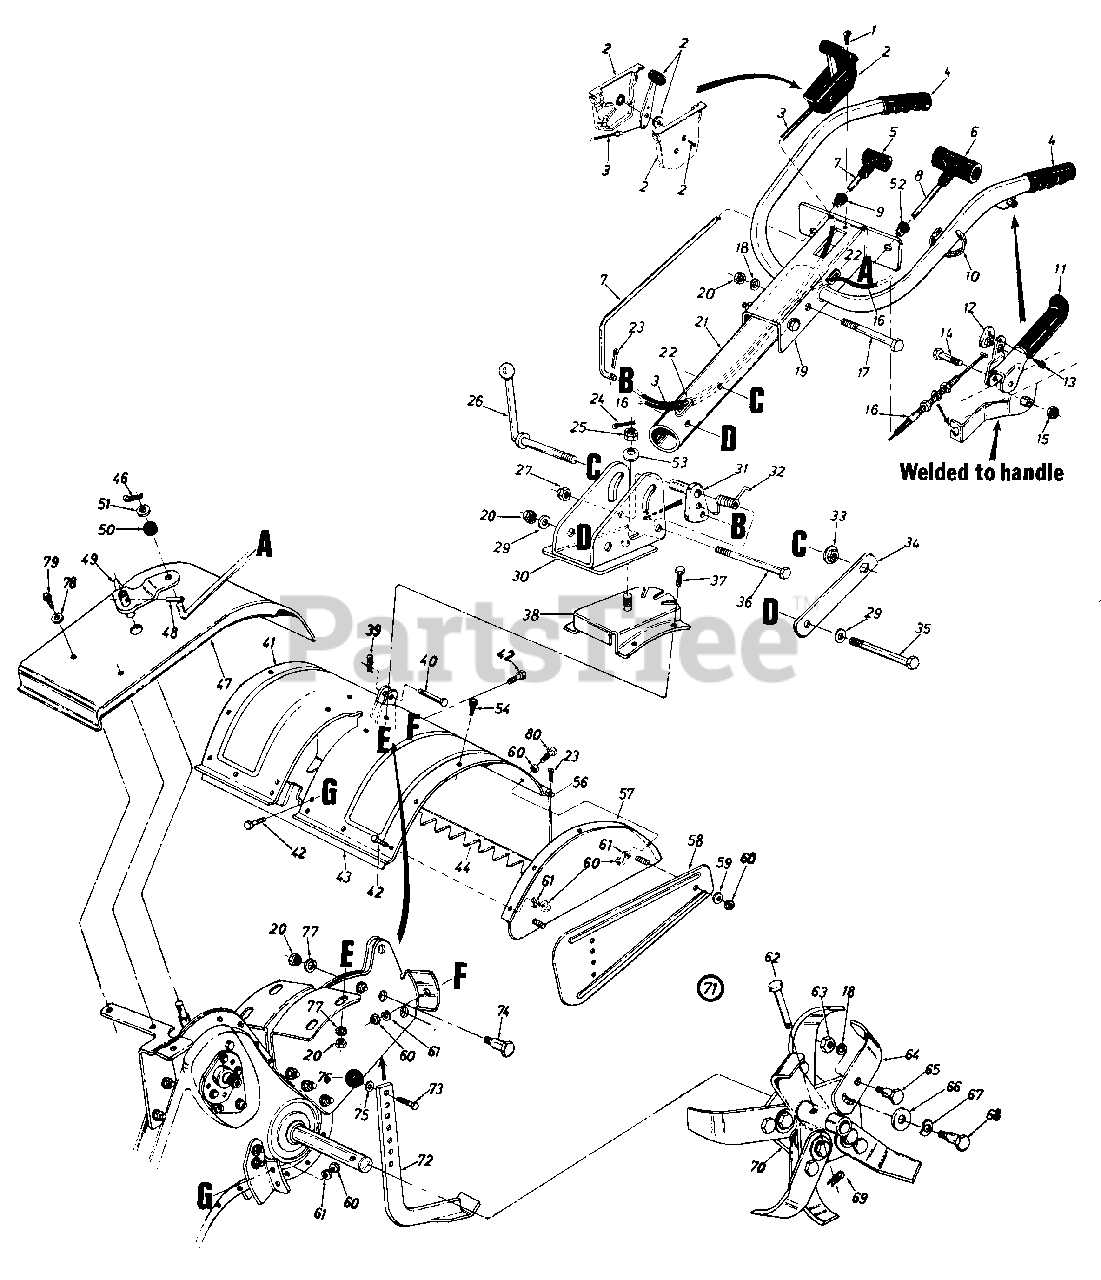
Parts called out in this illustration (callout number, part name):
1	Truss Mach. AB-Tap. Scr. #10 x 50" Lg.
2	Throttle Control Box Ass'y.
3	Throttle Control Wire
4	Handle Grip
5	Small "T" Knob
6	Large "T" Knob
7	Clutch Rod
8	Control Rod 37" Lg.
9	Snap On Bushing 3/8" Dia.
10	Cable Tie-Self Clinching
11	Clutch Grip Ass'y.-L.H.
12	Barrel Cable Hold Down
13	Hex B-Tap Scr. #10 x .44" Lg.
14	Hex Bolt 3/8-16 x 2.0" Lg.*
15	Hex Cent. L-Nut 3/8-16 Thd.
16	Clutch Control Cable 53" Lg.
17	Hex Bolt 3/8-16 x 3.00" Lg.
18	L-Wash. 3/8" I.D.-H.D.
23	Cotter Pin 3/32" Dia. x .75" Lg.*
24	Cotter Pin 3/32" Dia. x 1.25" Lg.*
25	Hex Slotted Nut 5/8-18 Thd.
26	Handle Adj. Crank
27	Hex Cent. L-Nut 3/8-16 Thd.
29	Bell-Wash. .4" I.D. x .87" O.D.
30	Handle Pivot Bracket
31	Positioner Crank Ass'y.
32	Spring Handle Adj.
33	Hex Flange Nut 3/8-24 Thd.
34	Bracket Hex Nut Retainer
35	Hex Bolt 3/8-16 x 3.25" Lg.*
36	Hex Bolt 3/8-16 x 3 00" Lg.- Gr. 8
37	Hex Bolt 3/8-16 x .75" Lg.
40	Clevis Pin .375" Dia.
43	Bracket Reinforcement-18"
46	Intern. Cotter Pin 5/16" Dia.
49	Shifting Crank Ass'y.
50	Rubber Washer .33" I.D.
51	Fl-Wash. .4" I.D. x 1.25" O.D.
52	Snap On Bushing 1/2" Dia.
53	Bell-Wash. .63" I.D. x 1.25n
54	Hex Wash. Tap Scr.
56	Tiller Flap Rod
60	Hex Nut 5/16-18 Thd.
61	L-Wash. 5/16" I.D.
62	Clevis Pin .375" Dia.
63	Hex Nut 3/8-24 Thd.
65	Shld. Bolt 1/2" Dia. x .175
66	Fl-Wash. .51" I.D. x l.50"
67	Bell-Wash. .515" I.D. x 1.14"
68	Shld. Bolt 1/2" Dia. x .320
69	Intern. Cotter Pin
73	Hex Bolt 3/8-16 x .75" Lg.
74	Shld. Bolt 1/2" I.D. x .62" Lg.
75	Fl-Wash. 3/8" I.D. x 5/8" O.D.
76	Ball Knob
77	L-Wash. 3/8" I.D.
78	Fl-Wash. .281" I.D. x .62"
79	Hex Wash. Self-Tap Scr. 1/4 -20 x 50" Lg.
80	Hex Bolt 5/16-18 x 11/4" Lg.
